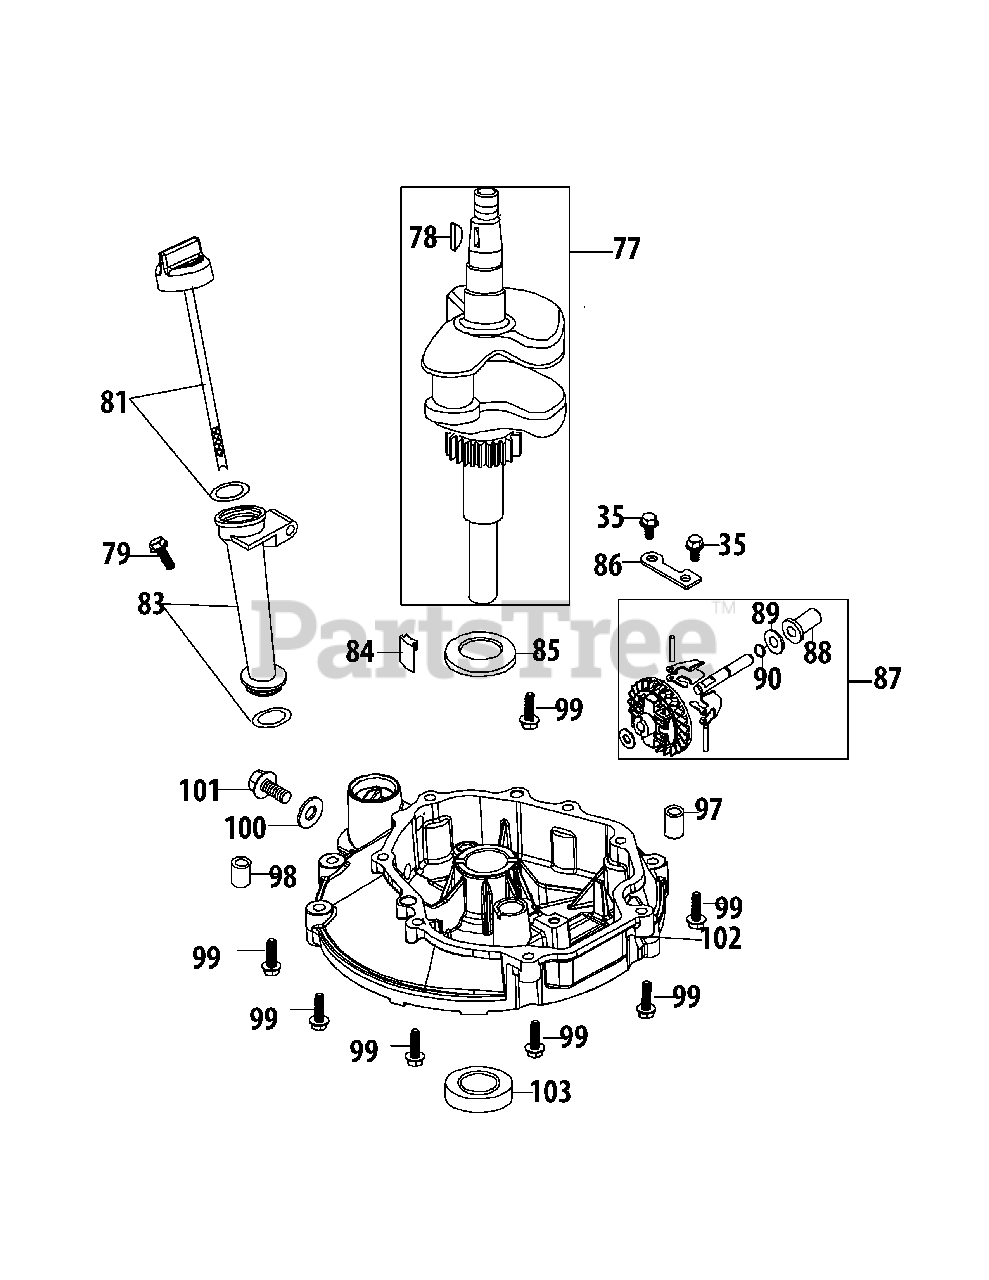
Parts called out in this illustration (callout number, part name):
35	BOLT M6-1 x 14 GR8.8
77	CRANKSHAFT ASSEMBLY
78	FLYWHEEL KEY
79	BOLT M6-1 x 35 GR8.8
81	DIPSTICK ASSEMBLY
83	DIPSTICK TUBE ASSEMBLY
84	OIL RETURN SEAL
85	THRUST WASHER
86	GOVERNOR GEAR MOUNTING PLATE
87	GOVERNOR GEAR/SHAFT ASSEMBLY
88	GOVERNOR CUP
89	WASHER-6.2 x 0.6 x 15
97	DOWEL PIN
98	DOWEL PIN
99	BOLT-M6-1 x 28 GR8.8
100	WASHER
101	OIL DRAIN PLUG
102	CRANKCASE COVER
103	LOWER CRANKSHAFT SEAL
